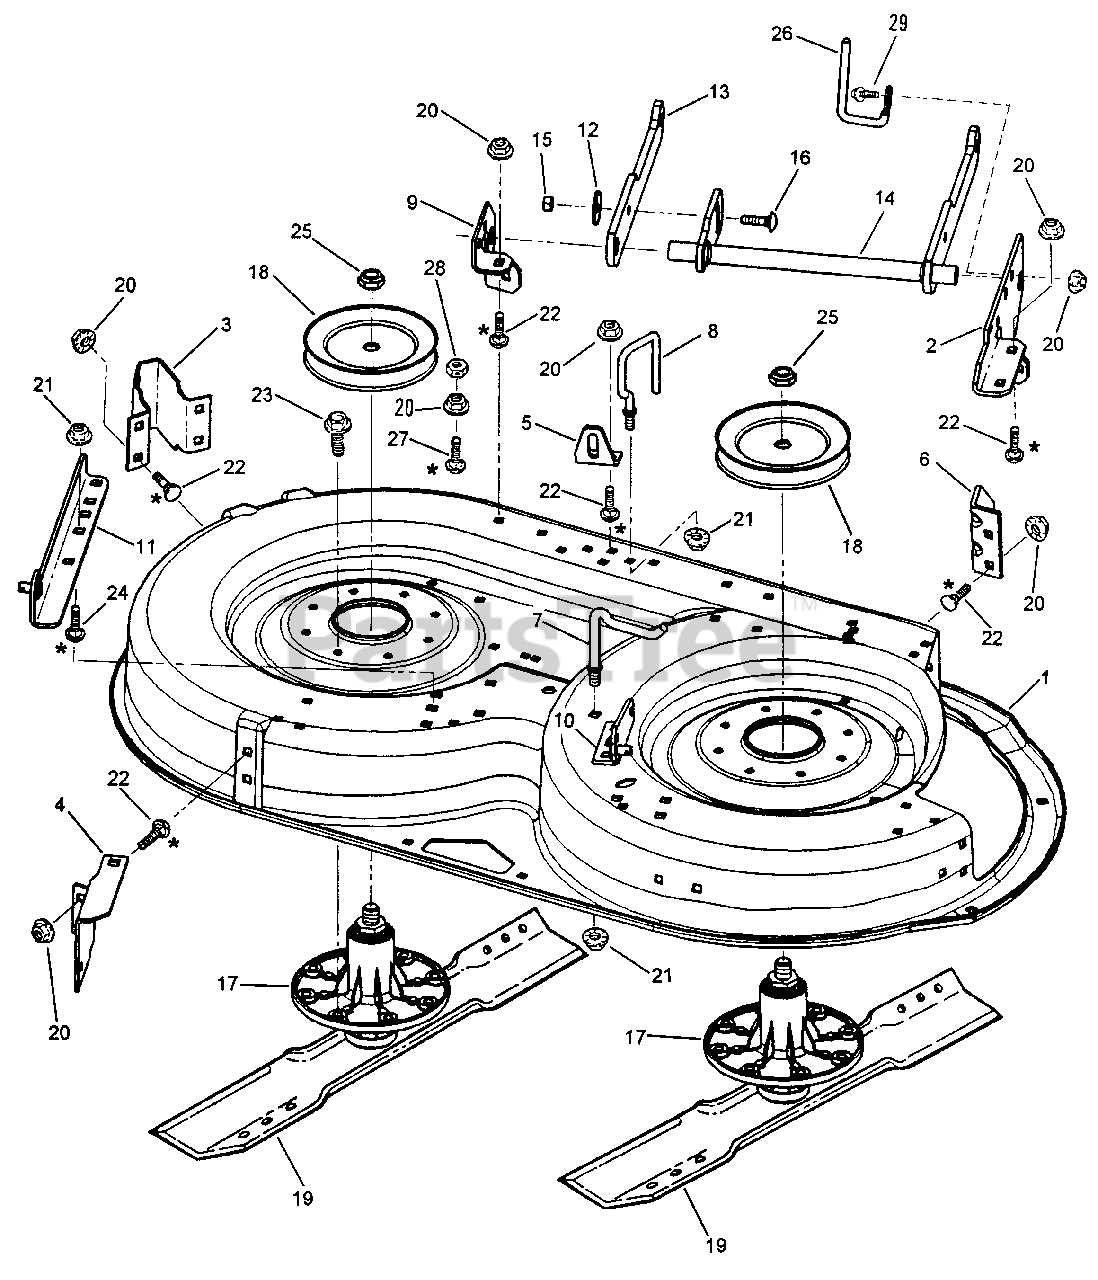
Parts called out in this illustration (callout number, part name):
1	DECK, 38" CUTTING
2	BRACKET, Front Linkage
3	BRACKET, LH Front Gage Wheel
4	BRACKET, LH Rear Wheel
5	ANGLE, Front
6	BRACKET, RH Front Gage Wheel
7	CRADLE, Spring
8	GUIDE, Belt Dual Spindle Brake
9	BRACKET, Front Lift Arm - LS
10	BRACKET, Sector Lift RH Rear
11	BRACKET, Sector Lift LH Rear
12	WASHER, Cone
13	FRONT LIFT ARM, 38 Deck
14	STRUCTURE, Front Lift Arm
15	NUT, 5/16-18 Hex Center Lock
16	BOLT, 5/16-18 x 1-1/8" Short Square Neck Carriage, Grade 5
17	ASSEMBLY, 38 Spindle
18	PULLEY, Spindle
19	BLADE, 38 Cutting Deck
20	NUT, 5/16-18 Flange Lock, Grade 5
21	NUT, 3/8-16 Hex Flange Lock
22	BOLT, 5/16-18 x 5/8" Short Square Neck Carriage, Grade 5
23	BOLT, 3/8-16 x 3/4" Hex Washer Self Tap
24	BOLT, 3/8-16 x 3/4" Short Square Neck Carriage, Grade 5
25	NUT, 5/8-18 Nyloc
26	GUIDE, Belt Side Rail
27	BOLT, 5/16-18 x 1-1/8", Square Neck Carriage, Grade 5
28	NUT, 5/16-18 Hex Center Lock, Grade 5
29	SCREW, 5/16-18 x 3/4" Hex Washer Self-tapping
